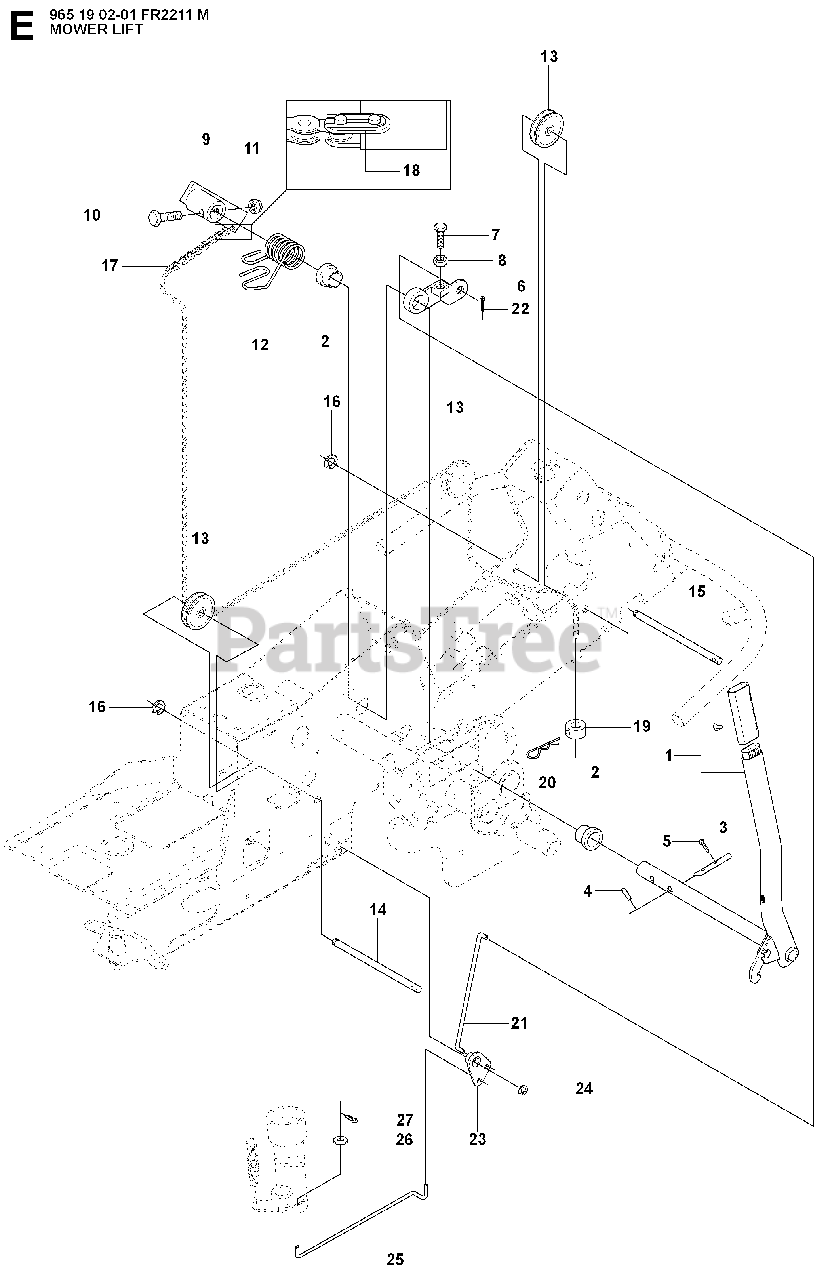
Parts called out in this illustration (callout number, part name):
1	LIFTING LEVER ASSY
2	BUSH
3	RP PIN
5	SPLIT PIN
6	LEVER CLUTCH
9	LIFTING ARM
16	LOCK RING
21	CONNECTION ROD
22	SPLIT PIN
24	RETAINING RING
25	CONNECTION ROD
27	SPLIT PIN
